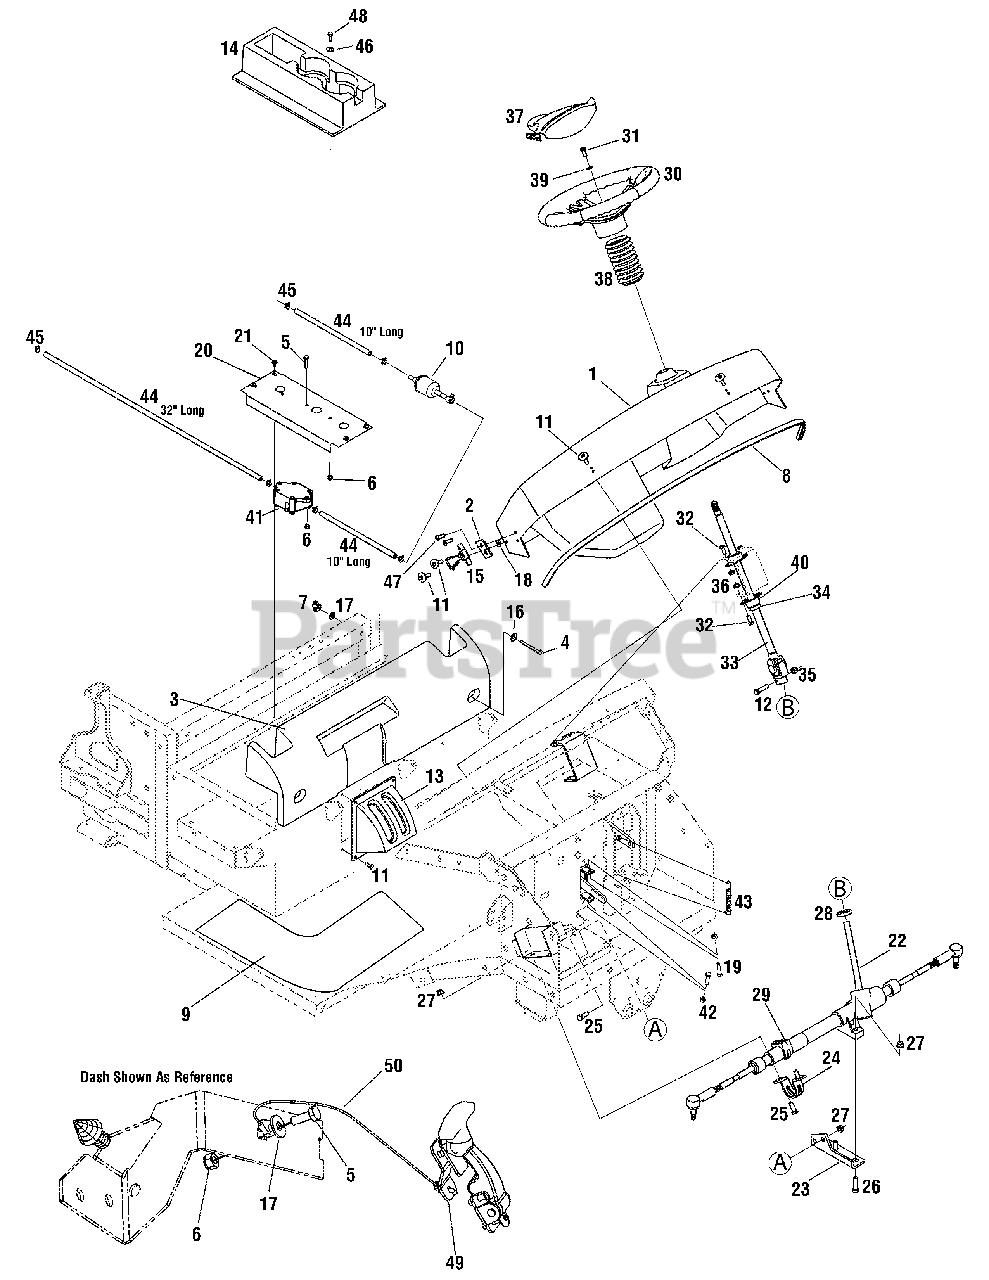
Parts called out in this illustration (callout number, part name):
1	Dash Panel
2	Hood Mounting Plate
3	Panel Cover
4	Hex Screw, 1/4-20 x 2.75
5	Hex Screw, 1/4-20 x.75, Gr5
6	Hex Lock Nut, Nylon, 1/4-20
7	Wing Nut, 1/4-20
8	Trim, Bulb Seal, 1/4
9	Foot Pad, Abrasive
10	Fuel Filter
11	Rivet, Pop,.188
12	Hex Screw, 3/8-16, 1.75, GR5
13	Panel, Shift Cover
14	Console, Cup Holder
15	Handle, Latch
16	Flat Washer, 349 x.875 x.04
17	Washer, Flat,.28 x.74 x.063
18	Washer, Flat,.194 x.62 x.063
19	Hex Screw, 5/16-18 x 1.25
22	Gear Assembly, Steering
25	Hex Screw, 3/8-16, 1.00, Gr8
26	Hex Screw, 3/8-16, 1.50, Gr8
27	Nut, Flange Lock, 3/8-16
28	Grommet, Steering Shaft
29	Bushing, Rubber
30	Wheel, Steering
31	Hex Screw, 5/16-18,.75, Gr5, Patch
32	Hex Screw, 5/16-18, .75, Gr5
33	Shaft, Steering, 5/8 Spline
34	Collar, .75
35	Nut, Hex Lock Nylon, 3/8-16
36	Nut, Flange Lock, 5/16-18
37	Cover, Steering Wheel
38	Bellow, Steering, 4.75 Lg
39	Washer, Bell,.340 x.872 x.060
40	Bearing, Flange,.75 ID, Self-Aligning
41	Pump, Fuel
42	Hex Nut, 5/16-18
43	Extension Spring
44	Fuel Line Hose
45	Clamp, Hose
46	Washer, Bell.39 x 1.38 x.062
47	Pop Rivet, 3/16 dia.x.450
48	Self-tap Screw5/16-18
49	Hood Cable Mount Bracket
50	Hood Cable
